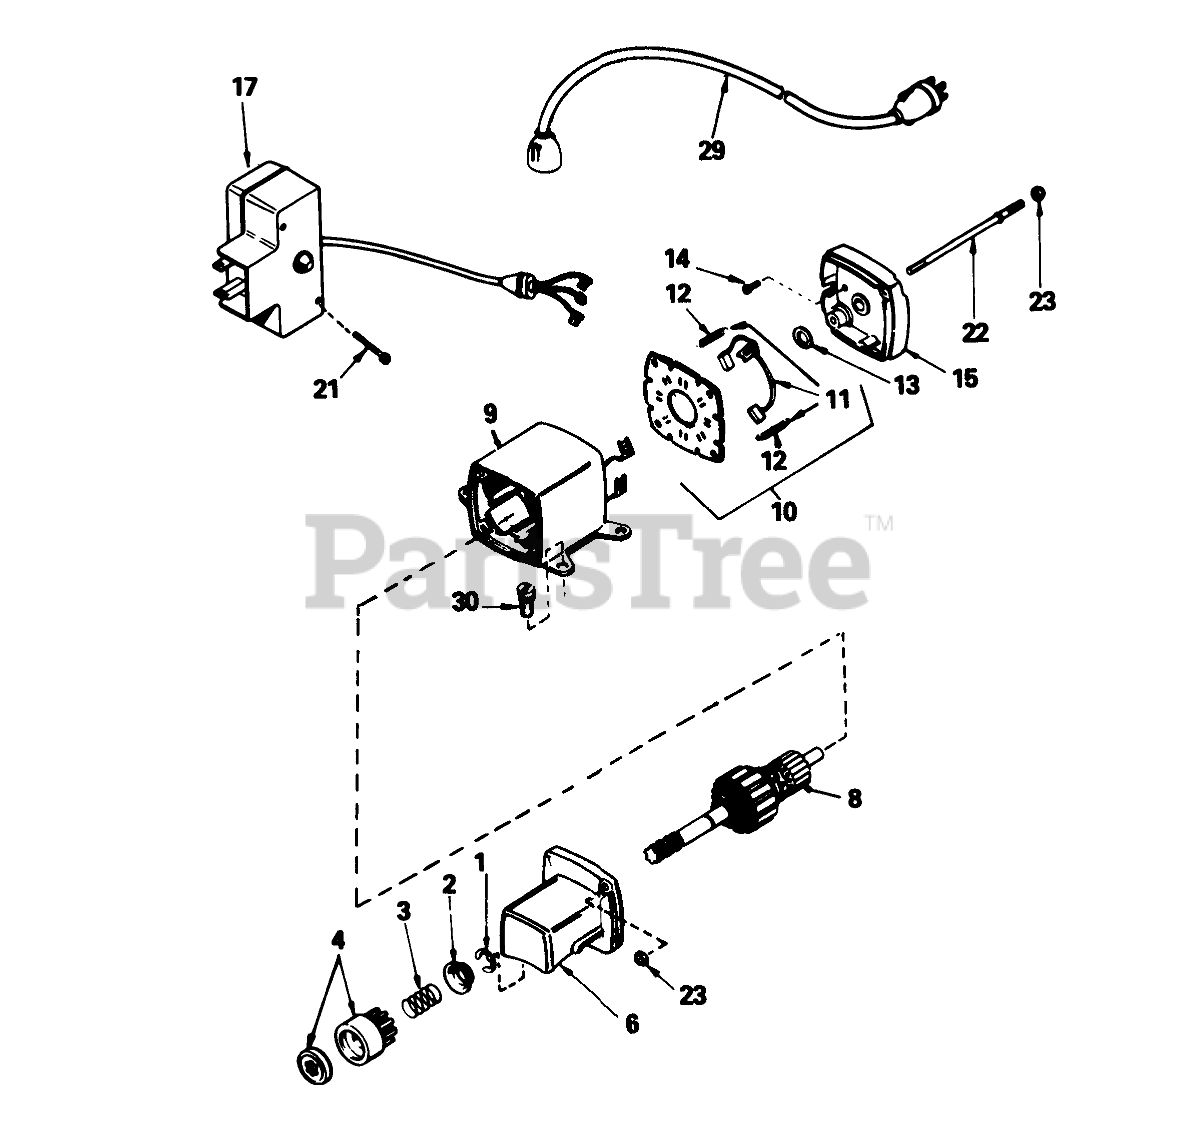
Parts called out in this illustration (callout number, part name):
1	Ring-Retainer
2	Retainer-Spring
3	Spring-Anti Drift
4	Nut & Gear
6	Cap Assy.-Drive End
8	Armature
9	Housing Assy.
10	Card Assy.-Brush (Incl. Ref. #11)
11	Brush & Spring Kit (Incl. Ref. #12)
12	1545D SUP TO W/3256
13	Washer-Thrust
14	Screw-Ground
15	Cap Assy.-Commutator End
17	Box Assy.-Switch
21	Screw
22	Bolt
23	Nut-Lock
29	Cord, Extension (10-)
30	Screw (T-30, 1/4-20 x 23/32)
